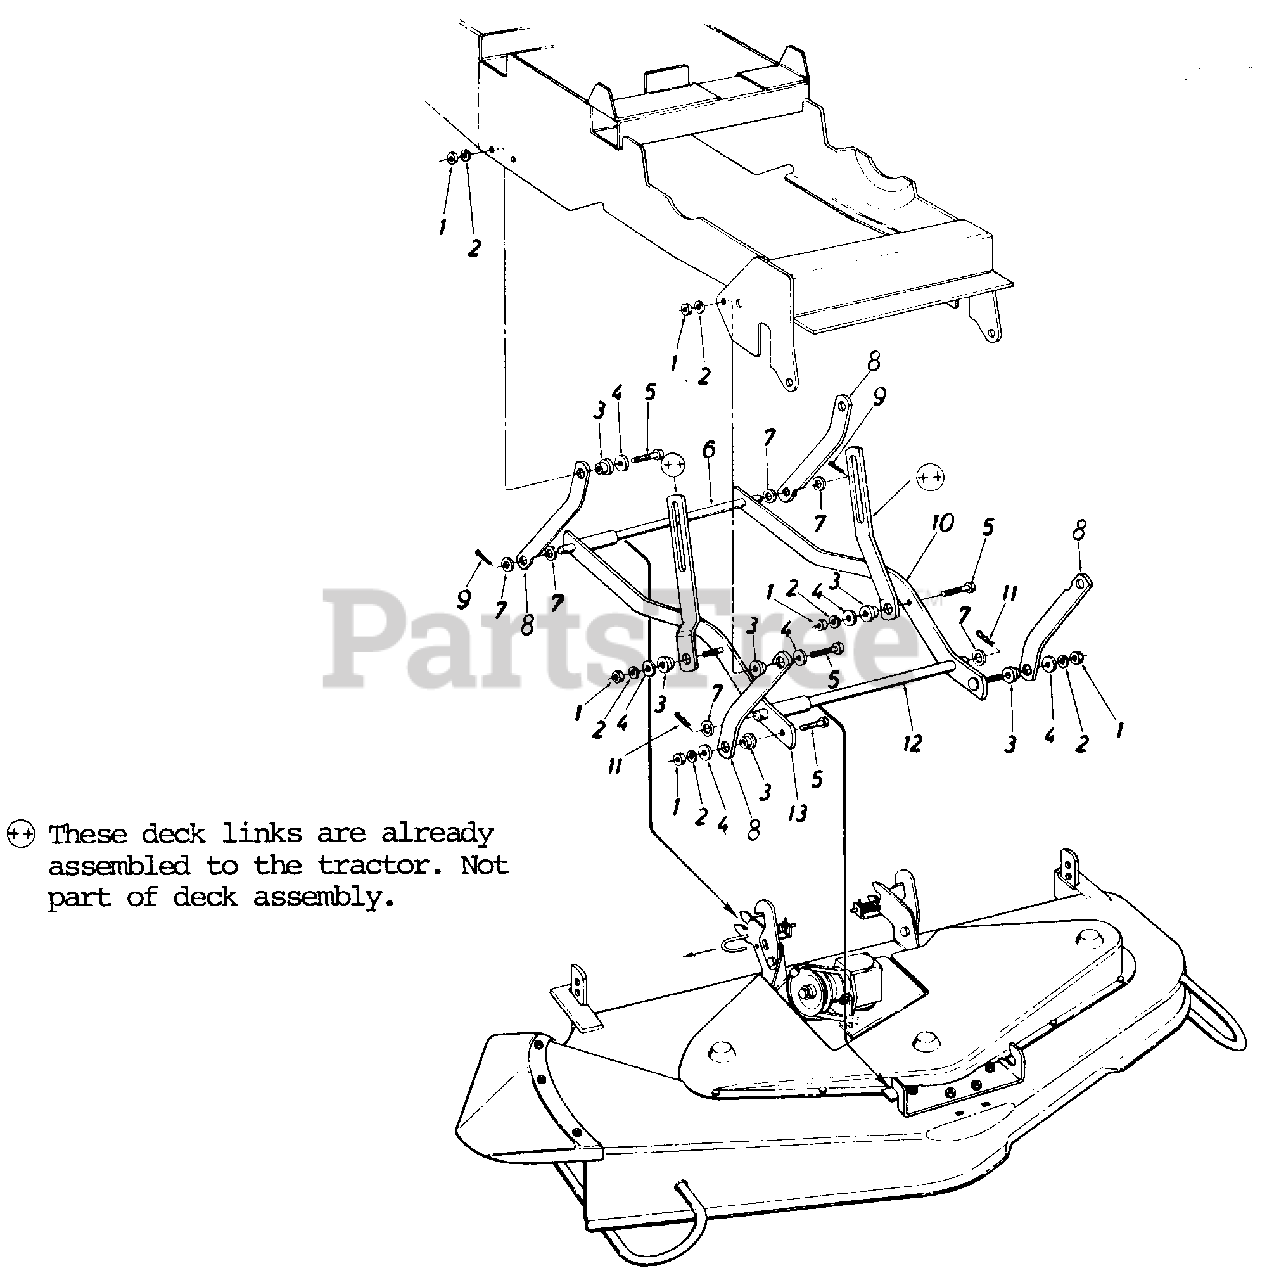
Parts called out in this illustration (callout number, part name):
1	Hex Nut 3/8-24 Thd.*
2	L.-Wash. 3/8" Scr. Heavy Duty*
3	Fl.-Wash. 3/8" I.D. x 1.0" O.D.
4	Shoulder Spacer . x 1.0" O.D.
5	Hex Scr. 3/8-24 x 1.50" Lg. Grade 5
6	Cross Shaft Ass'y.-Rear
7	Fl.-Wash. 5/8" I.D. x 1-1/8"0.D.
10	Lift Arm Link-L.H.
11	Hair Pin Cotter
12	Cross Shaft Ass'y.-Front
13	Lift Arm Link Ass'y.-R.H.
